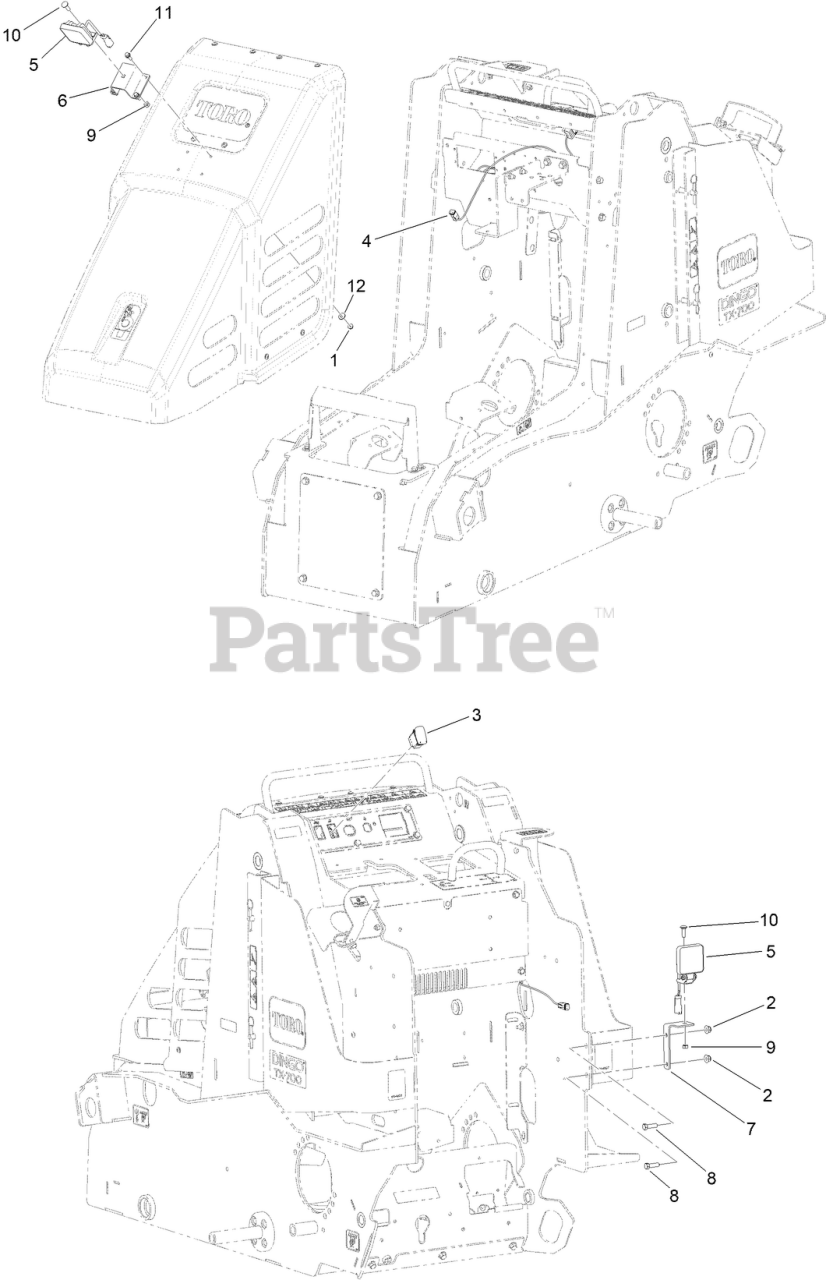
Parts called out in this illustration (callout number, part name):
1	NUT-HF
2	NUT-HF, NI
3	SWITCH
4	HARNESS-WIRE, WORK LIGHT
5	LIGHT-WORK, LED
6	BRACKET-LIGHT
7	BRACKET-LIGHT, REAR
8	SCREW-HH
9	NUT-HEX
10	SCREW-CARR
11	SCREW-HHF
12	WASHER-FLAT
